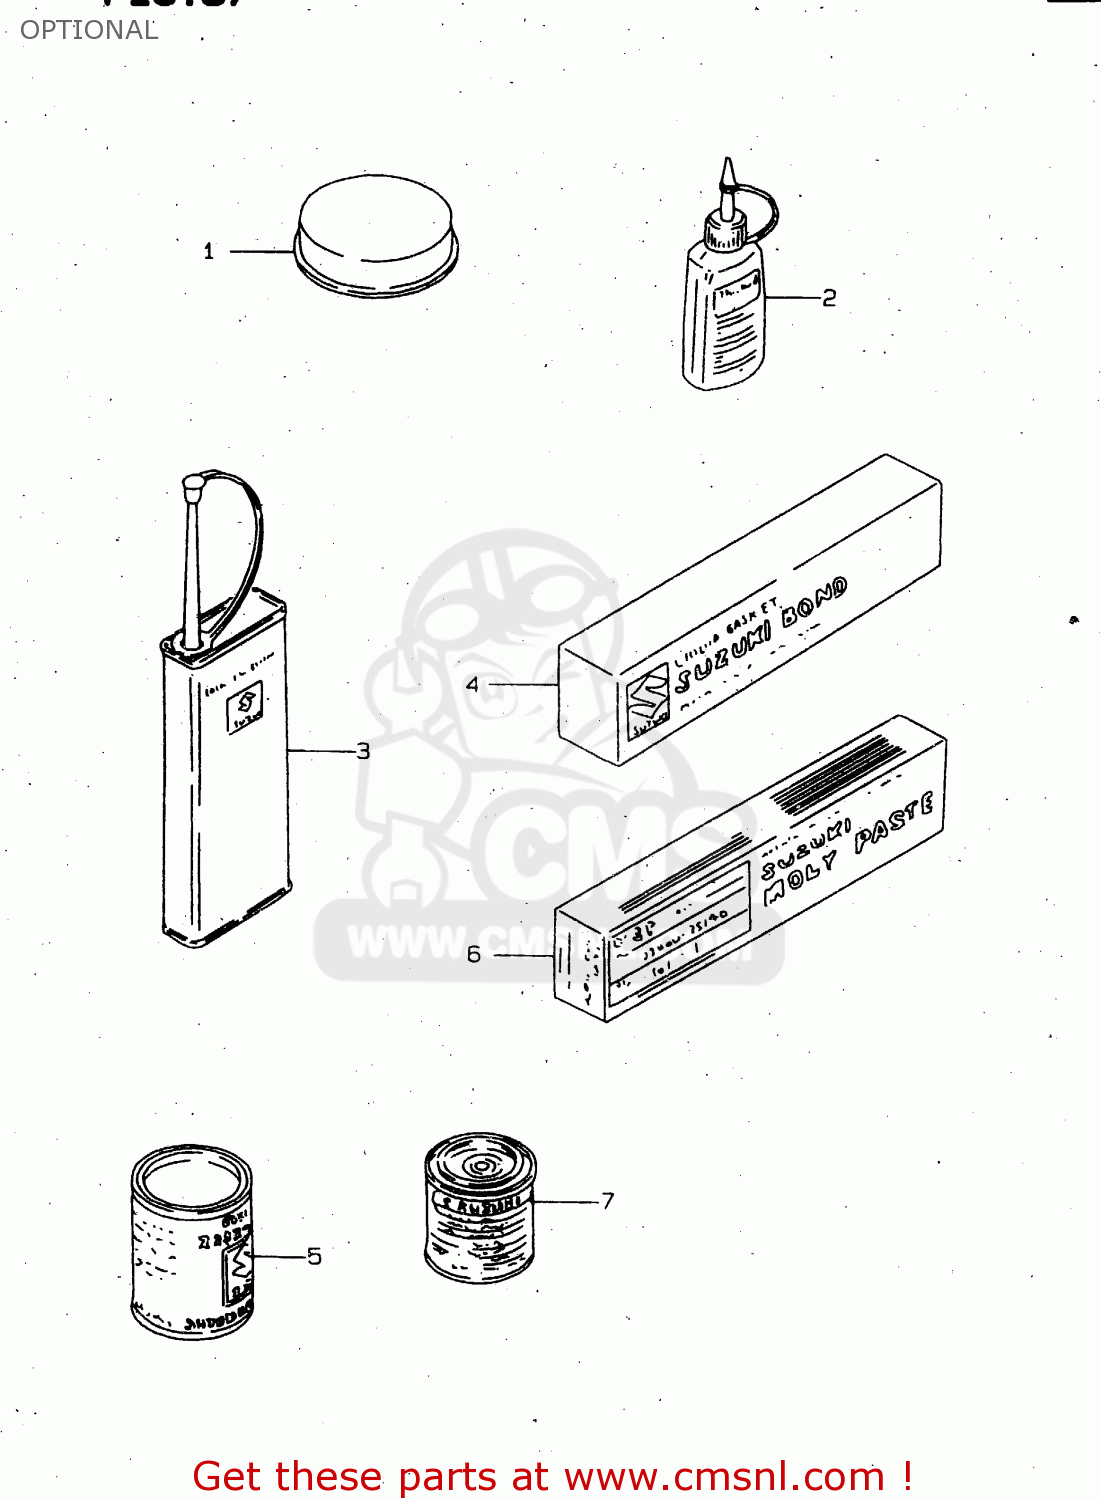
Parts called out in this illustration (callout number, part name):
1	GREASE,PBC FOR BRK PAD 20G
2	THREAD LOCK NO.1342
3	THREAD LOCK NO.1401 CLEAR 200G
4	LIQUID GSKT NO.1215 250G
5	GREASE(C)EP2 LITHIUM 150G
6	SUZUKI MOLY PASTE
7	PAINT,BLACK
